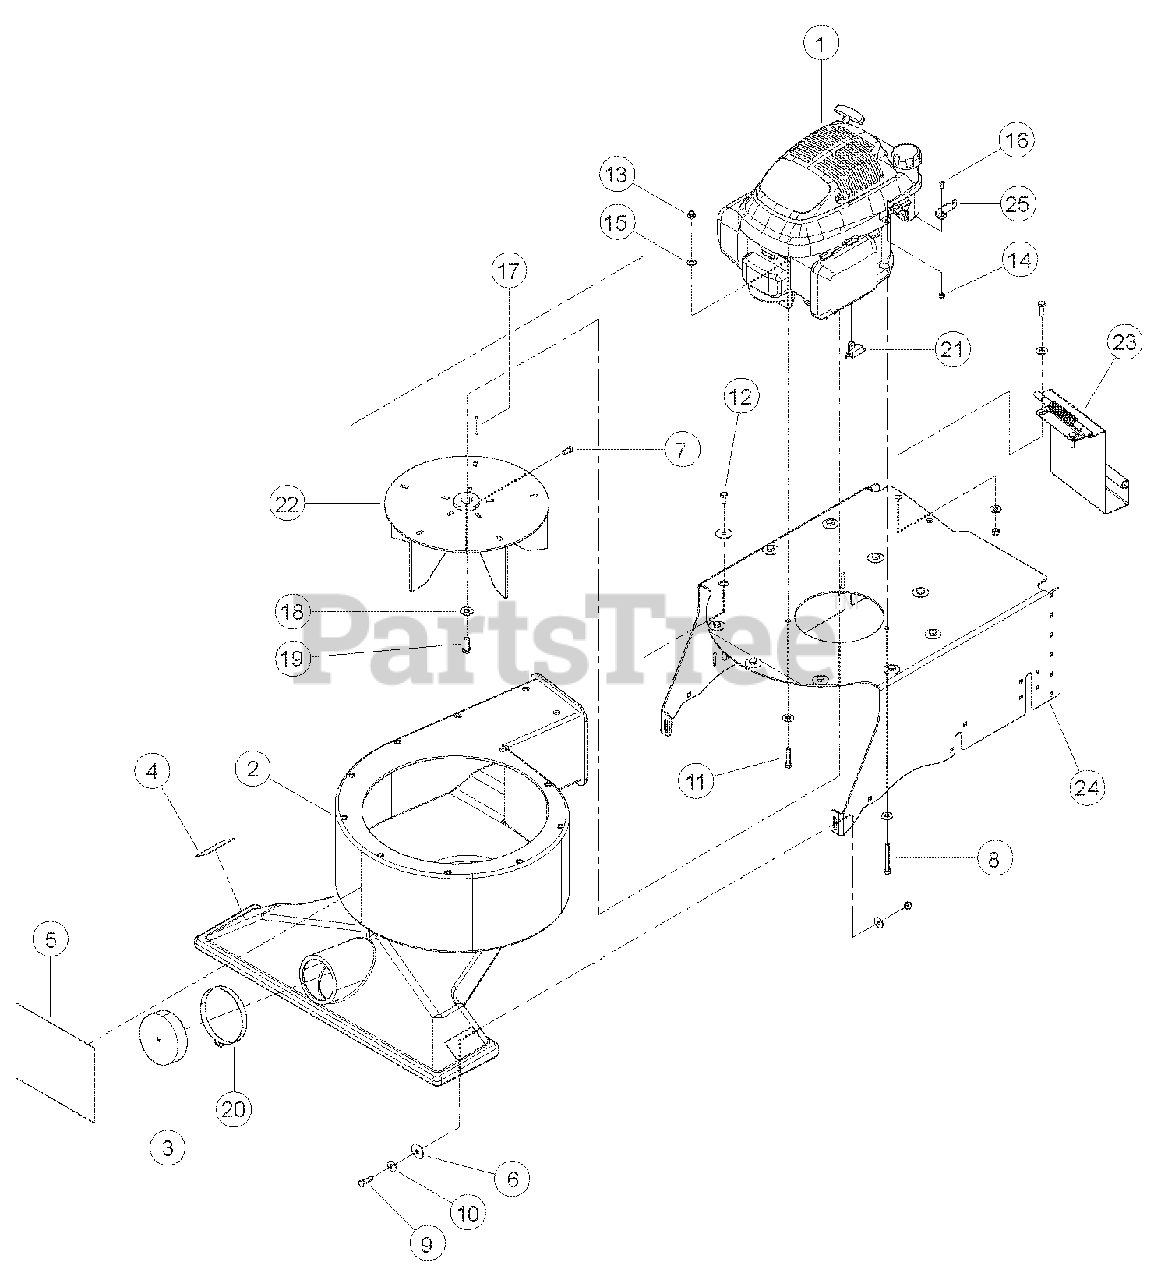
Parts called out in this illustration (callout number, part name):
1	ENGINE, 5.5 HP HONDA GCV
1	ENGINE, 190CC B&S INTEK/IC VERTICAL
2	ASSY., FAN HOUSING W/INTAKE
3	CAP, ROUND VINYL (4 X 1)
4	DECAL, DANGER
5	DECAL, ECHO BEARCAT
5	DECAL, CRARY BEARCAT
6	WASHER, 5/16 FENDER ZP
7	SCREW, 5/16-18 X 5/8 SQ HD SET
8	BOLT, 5/16 X 2-1/2 HEX HD GR5 ZP
8	BOLT, 5/16-18 X 1-3/4 HCS GR5 ZP
9	BOLT, 5/16 X 1 HHCS GR5 ZP
10	WASHER, 5/16 FLAT ZP
11	BOLT, 5/16 X 1-1/2 HEX HD GR5 ZP
12	BOLT, 5/16 X 5/8 HEX HD GR5 ZP
13	NUT, 5/16 NE NYLOCK ZP
14	NUT, 10/24 NYLOCK TYPE NM, ZP
15	WASHER, 5/16 SAE FLAT ZP
16	SCREW, MCH 10-24 X 1/2 PAN HD, PH ZP
17	KEY, 3/16 SQUARE X 1-1/4 LONG PLAIN
18	WASHER, 3/8 GR8 USS ZP
19	BOLT, 3/8 X 1 HHCS GR5 NF ZP
20	CLAMP, 4 IN. HOSE
22	WELDMENT, BEARVAC ROTOR
23	ASSEMBLY, EXHAUST DOOR
24	SUPPORT, BEARVAC FRAME
